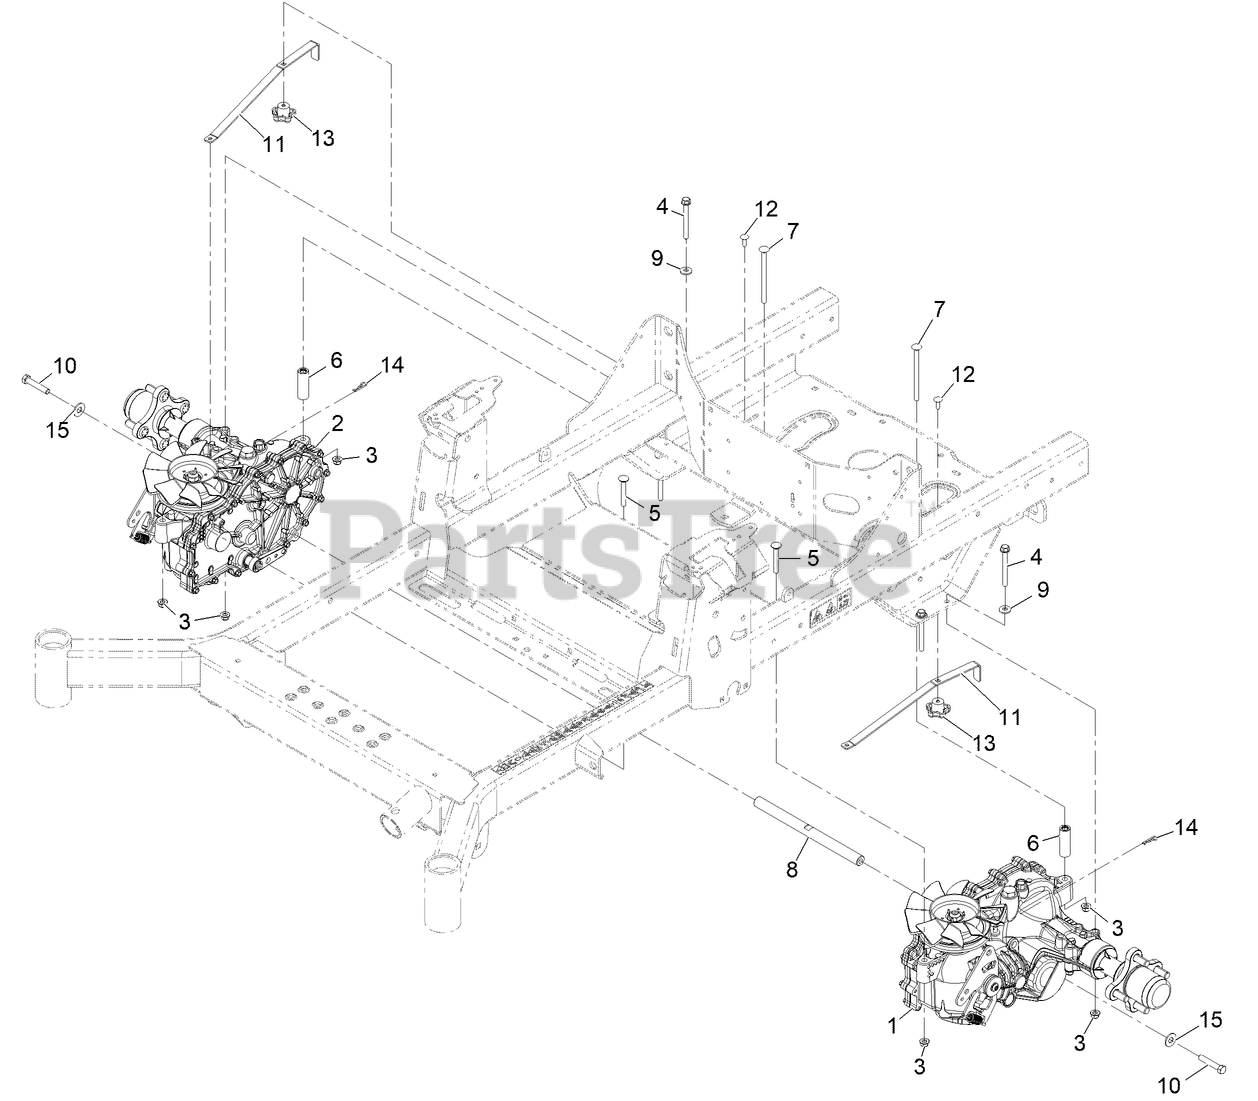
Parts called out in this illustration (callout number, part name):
1	TRANSAXLE ASM
2	TRANSAXLE ASM
3	NUT-HF, NI
4	SCREW-HHF
5	BOLT-CARR
6	SPACER, HYDRO
7	Bolt-Carriage 5/16-18 X 1 1/4
8	SHAFT-SPACER
9	WASHER-SPRING
10	SCREW-HH W/LOCTITE
11	ARM-BYPASS, HYDRO
12	BOLT-CARR
13	KNOB-HANDLE
14	PIN-COTTER
15	WASHER-FLAT
